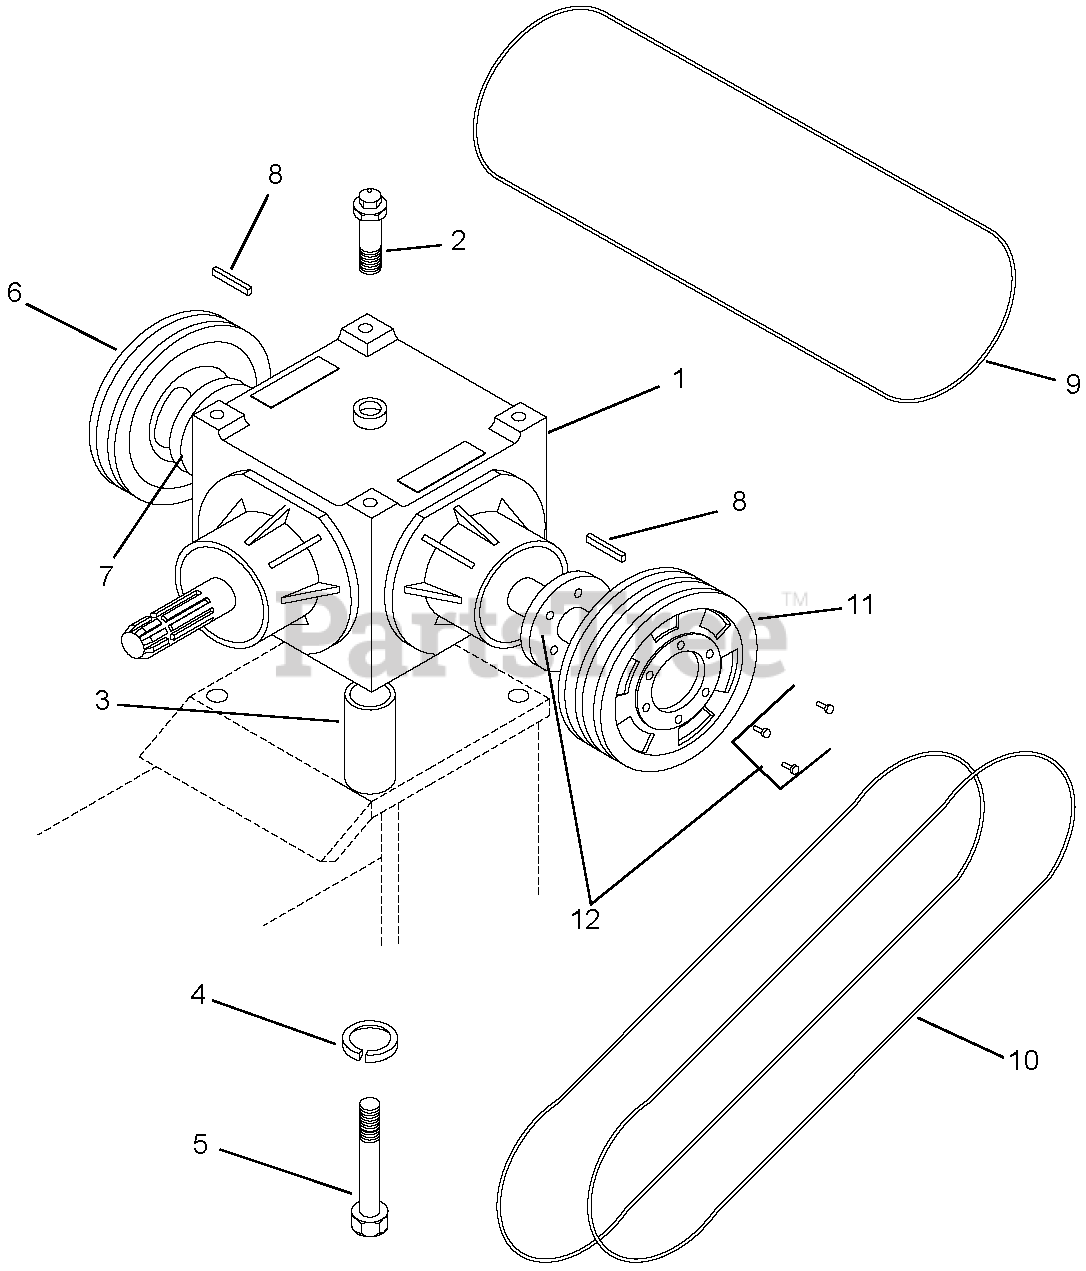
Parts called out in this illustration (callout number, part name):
1	Gearbox Assembly
2	Plug, Valve Vent
3	Spacer, Gearbox Mounting
4	Washer, Lock .50
5	Cap Screw, Hex Head .50-13 x 3
6	Pulley, 1-Belt 7.0 PD
7	Bushing 1.125
8	Key .25 x .25 x 2.00
9	V-Belt BX78
10	V-Belt BX70
11	Pulley, 2 Belt 7" Dia.
12	Bushing, 1-1/8 SK
